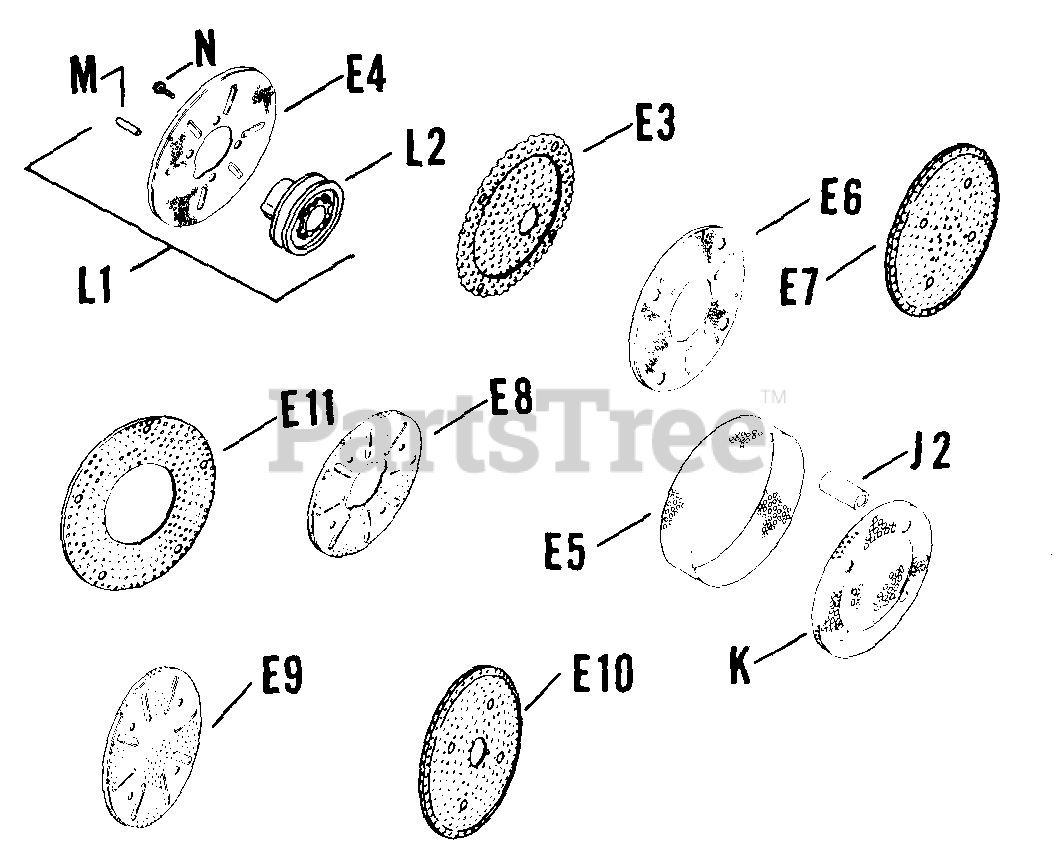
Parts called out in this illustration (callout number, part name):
E4	SCREEN - DISCONTINUED
L1	CUP - USE 41 071 05
L2	CUP - USE 41 109 02
M	PIN - DISCONTINUED
N	SCREW - USE X-67-46
